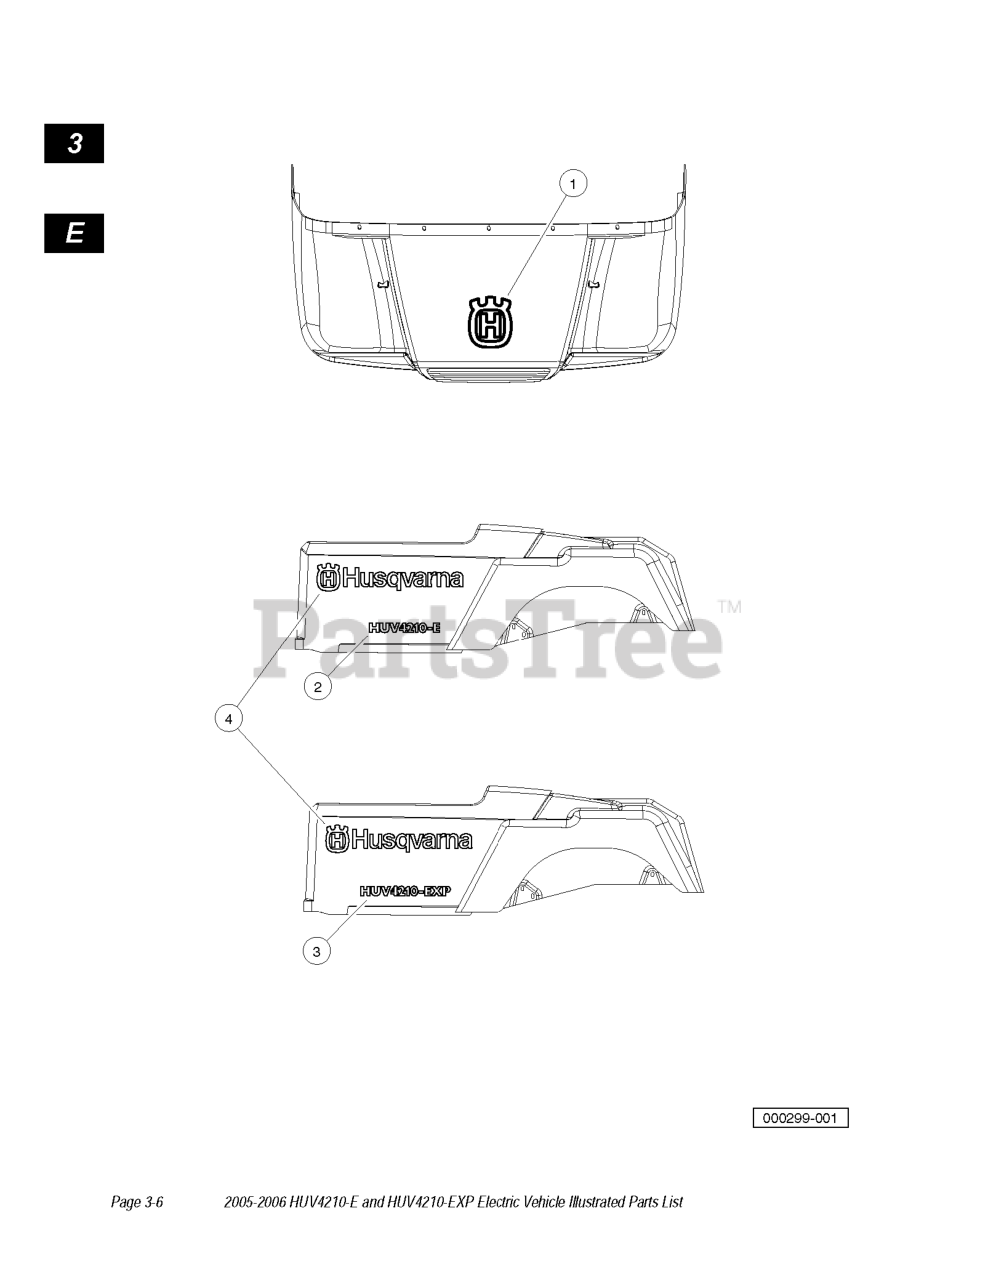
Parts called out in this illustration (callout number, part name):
1	DECAL HUSQ TOP
3	DECAL ,HUSQ, SIDE, EPLUS
4	DECAL, HUSQ, SIDE
